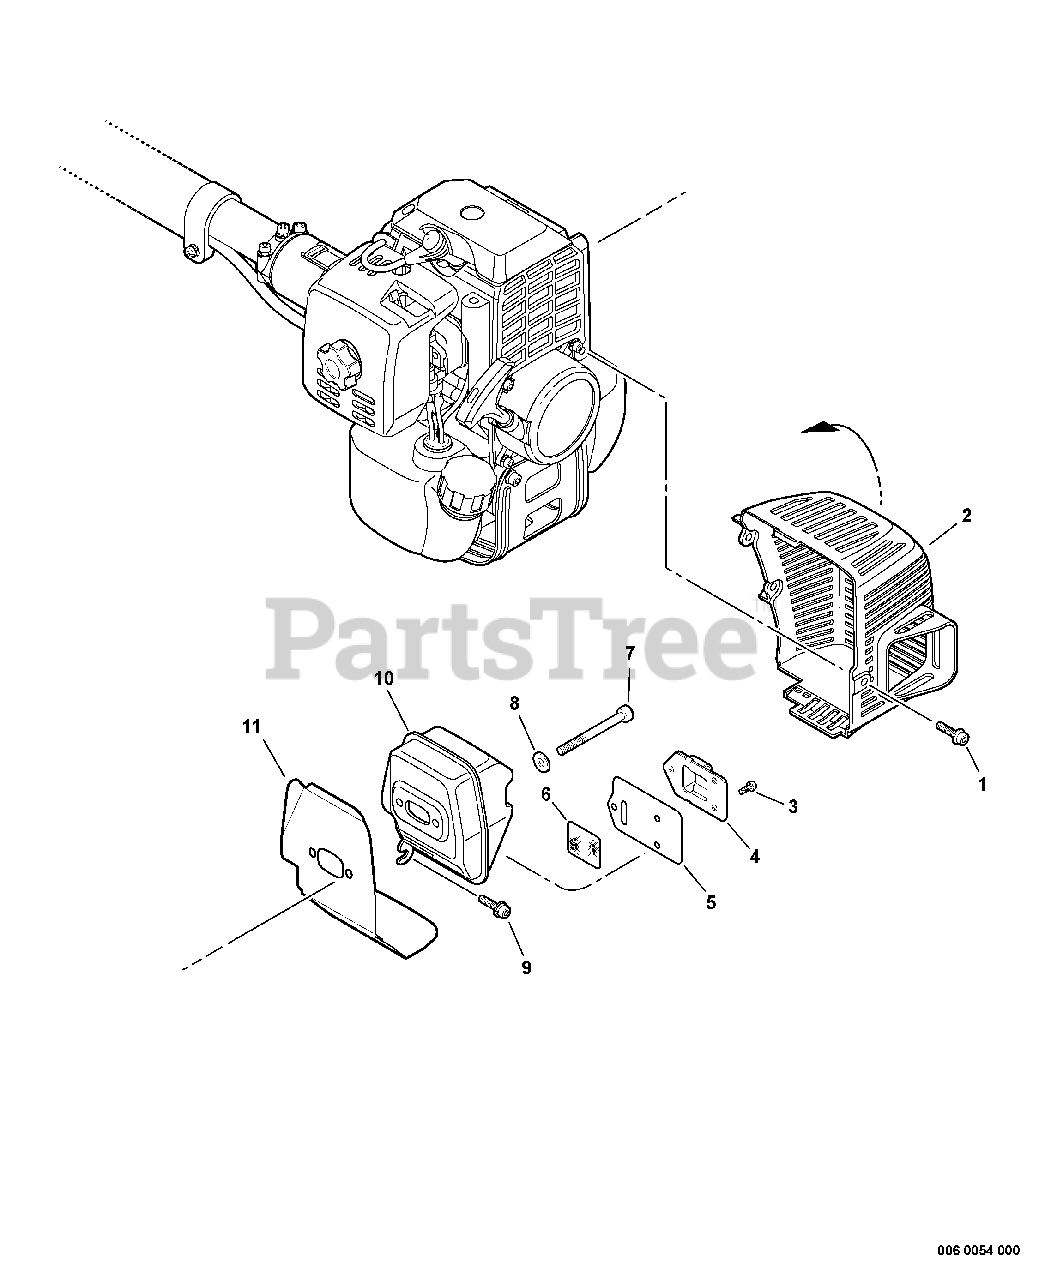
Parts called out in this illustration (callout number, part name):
1	BOLT 5×14
2	COVER, MUFFLER
3	SCREW 4×10
4	GUIDE, EXHAUST
5	GASKET, EXHAUST
6	SCREEN, SPARK ARRESTER
7	BOLT 5×60
8	WASHER, FLAT 5.5×10×0.8
9	BOLT 5×12
10	MUFFLER
11	SHIELD, EXHAUST
